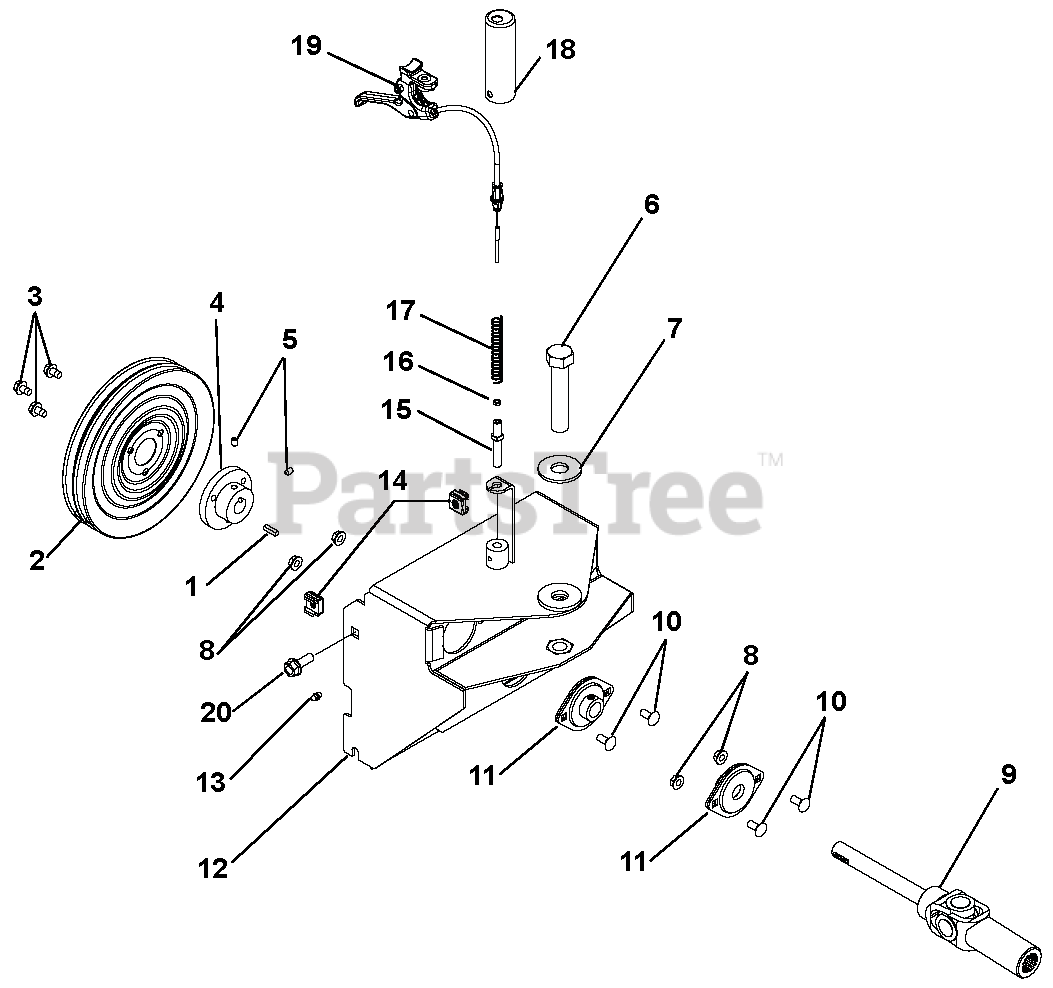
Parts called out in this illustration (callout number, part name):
1	KEY-SQ .188X.75X.188
2	PULLEY, SPIN FORM DUAL GROOVE
3	@SCR-TAP .31-18X.50 HWH TR YWZ
4	HUB, PULLEY
5	SCR-SET .25-20X.38 SKHCUPNL OH
6	HHCS .75-16 UNF X 3.75
7	@WSHR-FL-STL.812X2.00X.148YWZC
8	@NUT-LK-TOP-FLG .31-18 YWZC
9	DRIVELINE, SERIES 07
10	@BLT-RDHDSQNK .31-18X.75 G5YZ
11	BEARING, 3/4" FLANGETTE
12	MTG FRAME, MCD ARIENS
13	FTG-LUBE .25-28X.256 YWZC
14	NUT-RETNR .38-16 TINRMAN
15	PIN, SWING MCD-TRIGGER RELEASE
16	@NUT-HEX 10-24 YWZC
17	SPRING, COMPRESSION .51"X3.5"
18	CAP, VINYL MODIFIED
19	CABLE, CONTROL SWING-MCD
20	BLT-SERHFWH .38-16X.75 YWZC
